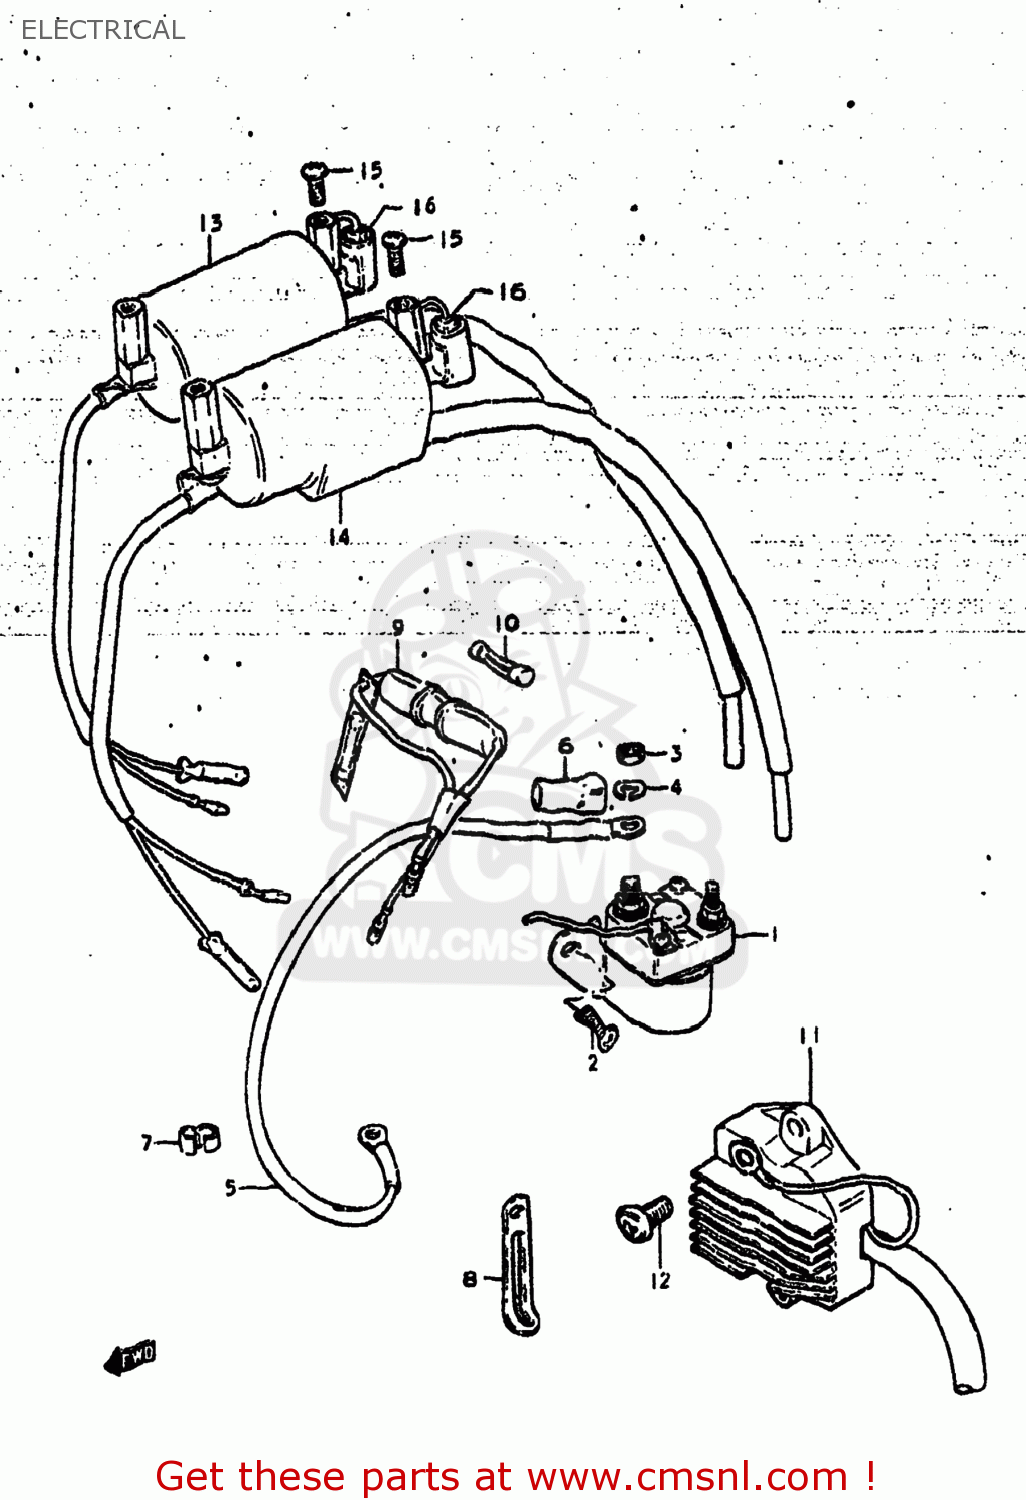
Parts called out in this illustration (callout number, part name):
1	RELAY ASSY,STARTING MOTOR
2	SCREW
3	NUT 6MM
4	LOCK WASHER
5	WIRE,STARTER MOTOR LEAD
6	CAP,STARTER RELAY
7	CLIP
8	CLAMP L:35
9	BOX ASSEMBLY,FUSE
10	FUSE(15A)
11	RECTIFIER ASSEMBLY
12	SCREW
13	COIL ASSEMBLY,IGNITION
14	COIL ASSEMBLY,IGNITION
15	SCREW
16	CONDENSER
